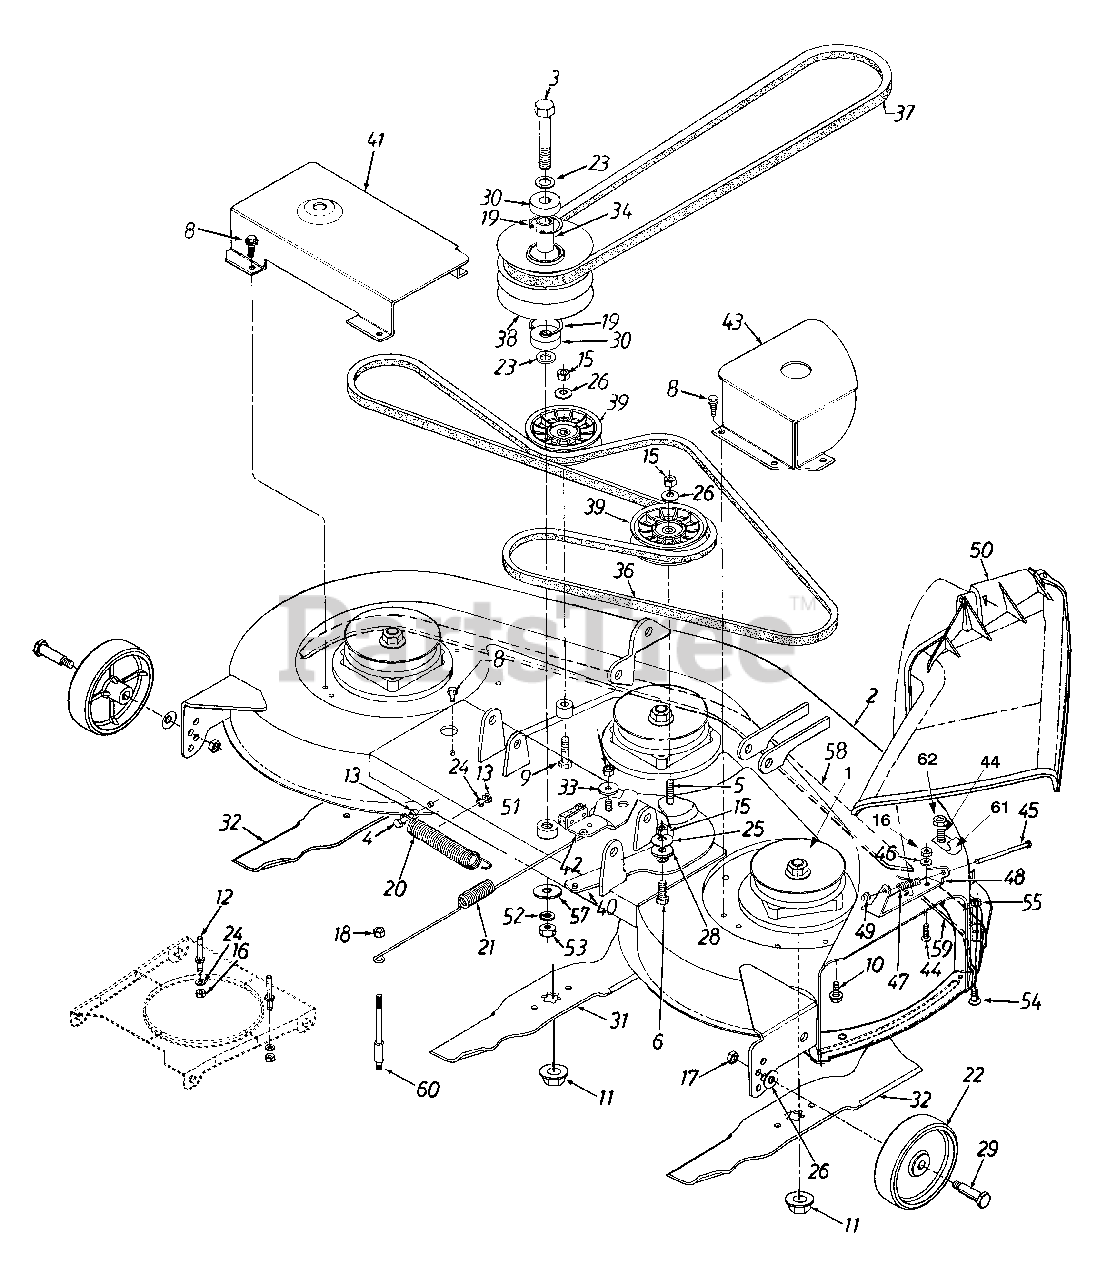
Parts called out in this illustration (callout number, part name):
1	Blade Spindle Ass'y.
4	Hex Bolt 1/4-28 x 1.25" Lg.
5	Hex Bolt 3/8-24 x 1.5" Lg.
6	Hex Bolt 3/8-24 x 1" Lg.
8	Hex Wash. Hd. TT-Tap Scr. 1/4-20 x .5"
9	Hex Bolt 3/8-24 x 2" Lg.
10	Hex Flange Bolt 5/16-24 x .75" Lg.
11	Hex Flange L-Nut 5/8-18 Thd.
12	Belt Guard Pin
13	Hex Nut 1/4-28 Thd.
15	Hex Nut 3/8-24 Thd.
16	Hex Nut 1/4-20 Thd. (Gr. 5)
17	Hex Top Jam Nut 3/8-16 Thd.
18	Hex Center L-Nut 5/16-18 Thd.
19	Int. Snap Ring
20	Ext. Spring .88" O.D. x 6.17"
21	Ext. Spring .788" O.D. x 15.5"
22	Deck Wheel
23	Fl-Wash. .635" I.D. x 1" O.D. x .06"
24	L-Wash. 1/4" I.D.
25	Bell-Wash. 3/8" x 1.125" x .062"
26	Bell-Wash. 3/8" x .87" x .064"
28	Shoulder Spacer .625" I.D. x .169"
29	Shld. Bolt .498" x 1.525"
30	Ball Brg. .625" I.D. x 1.574" O.D. x .47"
31	Blade 14.88" Lg.
32	Blade 16.28" Lg.
33	Shoulder Spacer
34	Spacer .635" I.D. x .088" O.D.
36	V-Belt
37	V-Belt
38	Pulley Double Deck 5" O.D.
39	Flat Idler Pulley 3.5 O.D.
44	Hex Bolt 1/4-20 x .62" Lg.
45	Hinge Pin
46	Bell-Wash. 1/4" I.D.
47	Torsion Spring
48	Hinge Mtg. Brkt.
50	Chute Ass'y. Comp.
51	Spacer .635" I.D. x 1" O.D.
52	L-Wash. 5/8" I.D.
53	Hex Nut 5/8-18 Thd.
54	Carriage Bolt 1/4-20 x .5" Lg.
55	Hex Sems Nut 1/4-20 Thd.
57	Fl-Wash. .635" I.D.
60	Return Spring Stud
61	Retainer Hook Bracket
62	Hex Lock Nut 1/4-20
